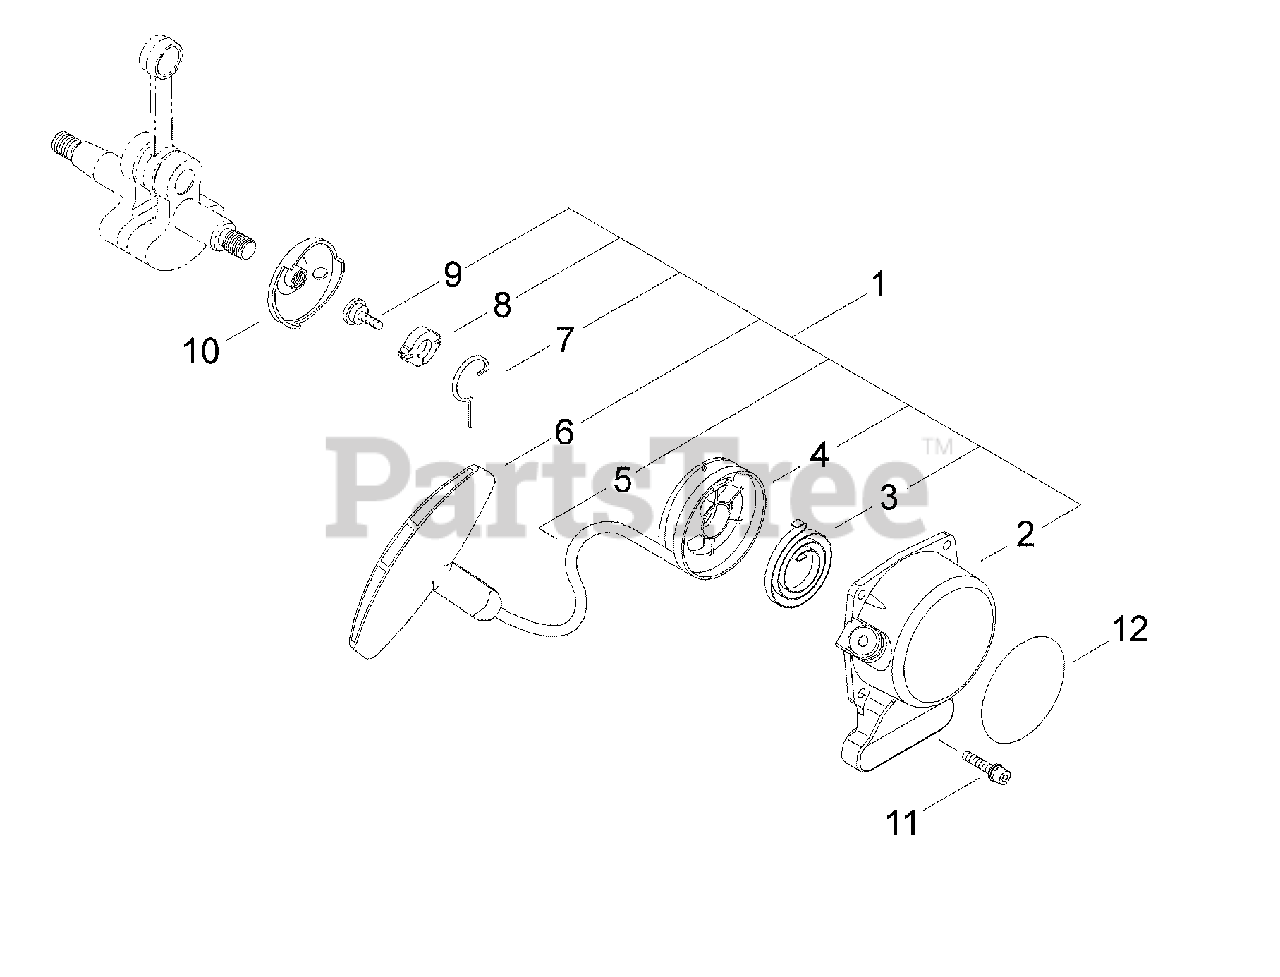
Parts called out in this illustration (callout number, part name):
1	STARTER ASSY, RECOIL
2	CASE, RECOIL STARTER
3	SPRING, RECOIL
4	REEL, ROPE
5	ROPE, STARTER
6	GRIP, STARTER
7	ARM, SWING
8	WASHER 5
9	SCREW 5
10	PULLEY, STARTER
11	BOLT M4×14
12	LABEL, SWISHER E4
